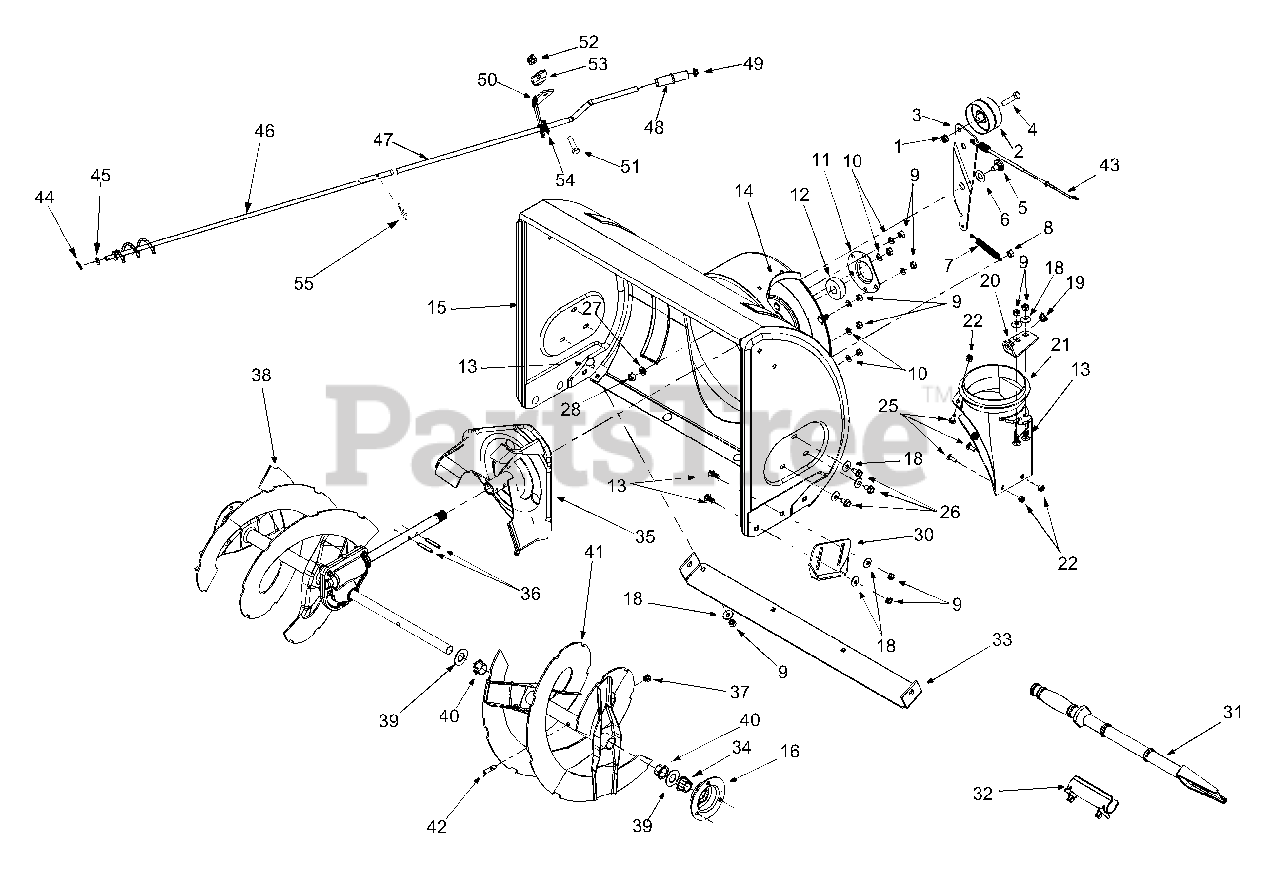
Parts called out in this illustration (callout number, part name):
1	Lock Jam Nut 3/8-24
2	Flat Idler
4	Hex Cap Screw 3/8-24 x 1.50
5	Shoulder Screw
6	Flat Washer,.565 x 1.25 x.02
7	Extension Spring
8	Hex Nut 5/16-18
9	Hex Nut 5/16-18
10	Lock Washer 5/16
11	Housing
12	Ball Bearing
13	Carriage Bolt 5/16-18 x.75
18	Bell Washer
19	Bushing
21	Chute Adapter
22	Hex Flange Lock Nut 1/4-20
25	Carriage Screw 1/4-20 x.75
26	Screw 5/16-12
27	Lock Washer 3/8
28	Hex Nut 3/8-16
31	Chute Clean-out Tool
32	Mount, Chute Clean-out Tool
34	Hex Flange Bearing
37	Lock Nut 5/16-18
39	Flat Washer
40	Flange Bushing
42	Shear Bolt 5/16-18 x 1.5
43	Drive Cable
44	Hairpin Clip
45	Flat Washer
48	Chute Crank Knob
49	Push Cap
51	Hex Screw 1/4-20
52	Hex Nut 1/4-20
53	Bell Washer
54	Plastic Bushing
55	Hairpin Clip
